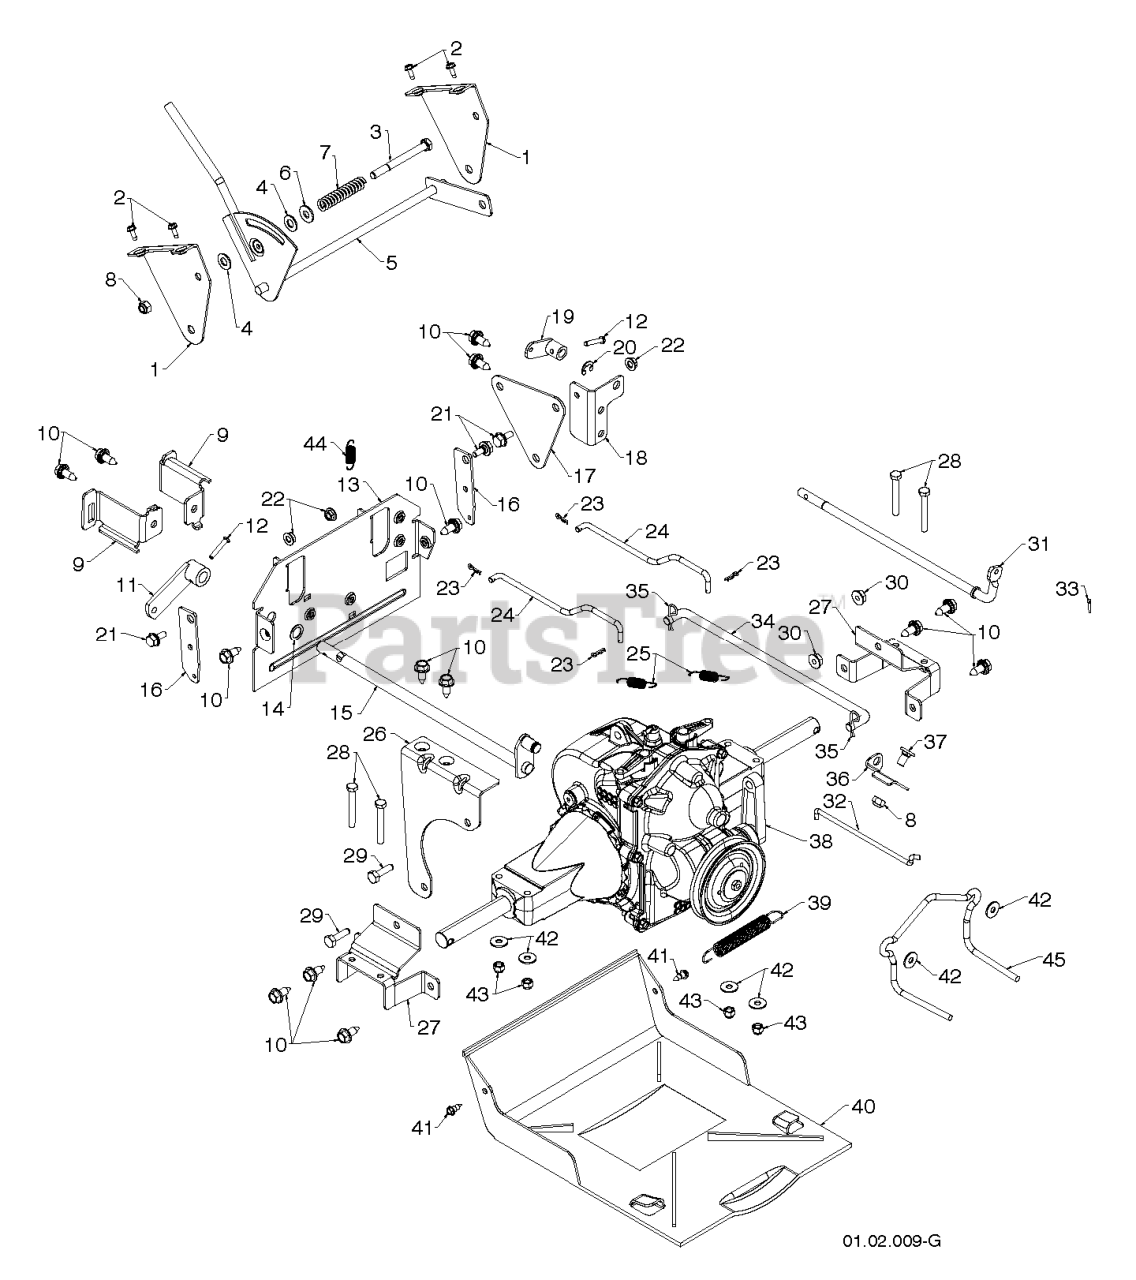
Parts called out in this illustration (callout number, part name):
1	BRACKET.SHIFT.HYDRO
3	SCREW 5/16-18 X 3.25
4	WASHER, NYLON FRICTION
5	CONTROL.WLD.HYD.II
6	WASHER.20X8.5
7	SRPING.FRICTION.HYDRO
8	NUT.71038.31-18.HEX.NYLOCK
9	BRACKET.CABLE.PNT.HYDRO
10	BOLT.HEX.HD.WASHER.5/16-18X.75
11	ARM, AUGER CONTROL
12	CLEVIS PIN
13	PLATE.REAR.HYDRO.PNT.ORANGE
14	THRUST WASHER
15	CONTROL.SHAFT.ASM
16	BRACKET.SPEED.PIVOT.YZP
17	BRACKET.SPEED.PIVOT.YZP
18	LEVER.STEER.CABLE.PNT.SNOW
19	ARM.HYD.CLUTCH
20	E-RING.RETAINER.REINFORCED.375
21	BOLT.SHOULDER.3/X.25
22	NUT.HEX.FLANGE.1/4
23	COTTER PIN (3 2)(2 2MC)
24	ROD.STEER.HYD
25	SPRING.RETURN
26	BRACKET.HYDRO.STABILIZER
27	BRACKET.TRANSMISSION.MOUNT
28	BOLT.HEX.1/4-20X2.00.HEX.HD.
29	BOLT RB
30	NUT.LOCK.5/16-18
31	SHAFT.HYD.CLUTCH
32	ROD.HYDRO CLUTCH
33	RETAINER CLIP
34	ROD.SPEED.CONT.HYD.SNOW
35	SPRING RETAINER
36	BRACKET.HYD.CLUTCH.
37	BOLT.CARRIAGE.5/16-18X
38	TRANSMISSION.HYDROII.PS
39	SPRING, BRAKE
40	PAN.BOTTOM.PLASTIC.SNOW
41	SCREW, HEX HEAD, TAPPING
42	WASHER
43	LOCKNUT.NYLOC.1/4-20
45	GUIDE BELT.HYDRO 2
